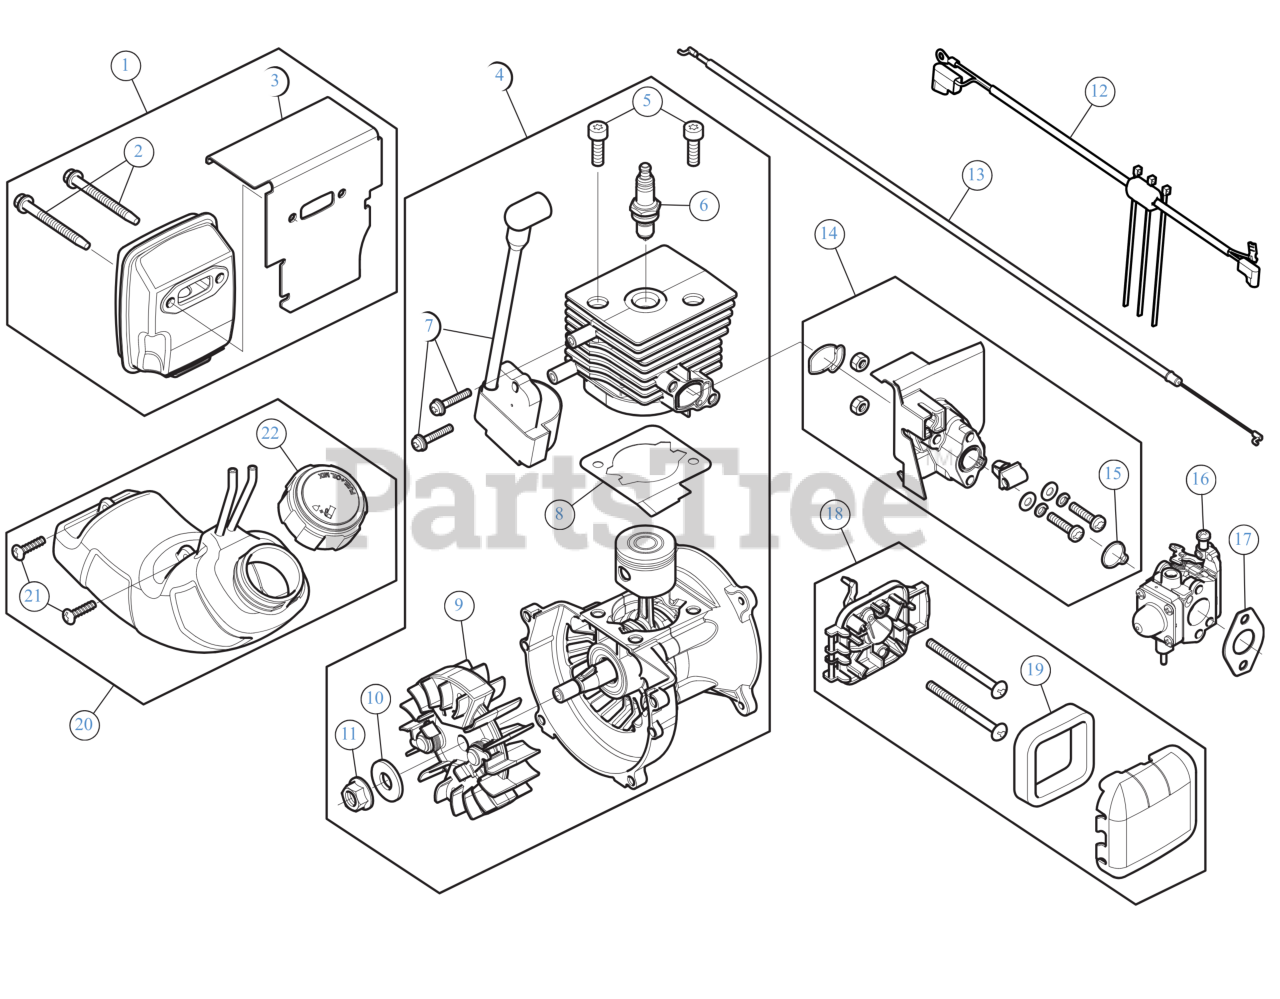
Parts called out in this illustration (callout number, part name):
1	MUFFLER ASSEMBLY 27CC
2	MUFFLER SCREW
3	MUFFLER GASKET
4	SHORT BLOCK
5	SCREW 1/4 x 20 x .8125
6	SPARK PLUG 14MM
7	MODULE ASSEMBLY MPP
8	GASKET CYL
9	FLYWHEEL ASSEMBLY
10	WASHER .406X1.0X.095
11	NUT 3/8-24
12	WIRE LEAD RFI
13	THROTTLE CABLE
14	INTAKE ASSEMBLY
16	CARBURETOR ASSEMBLY
17	GASKET CARB
18	AIR CLEANER ASSEMBLY
20	FUEL TANK ASSEMBLY
21	SCREW 8-16 x 3/4
